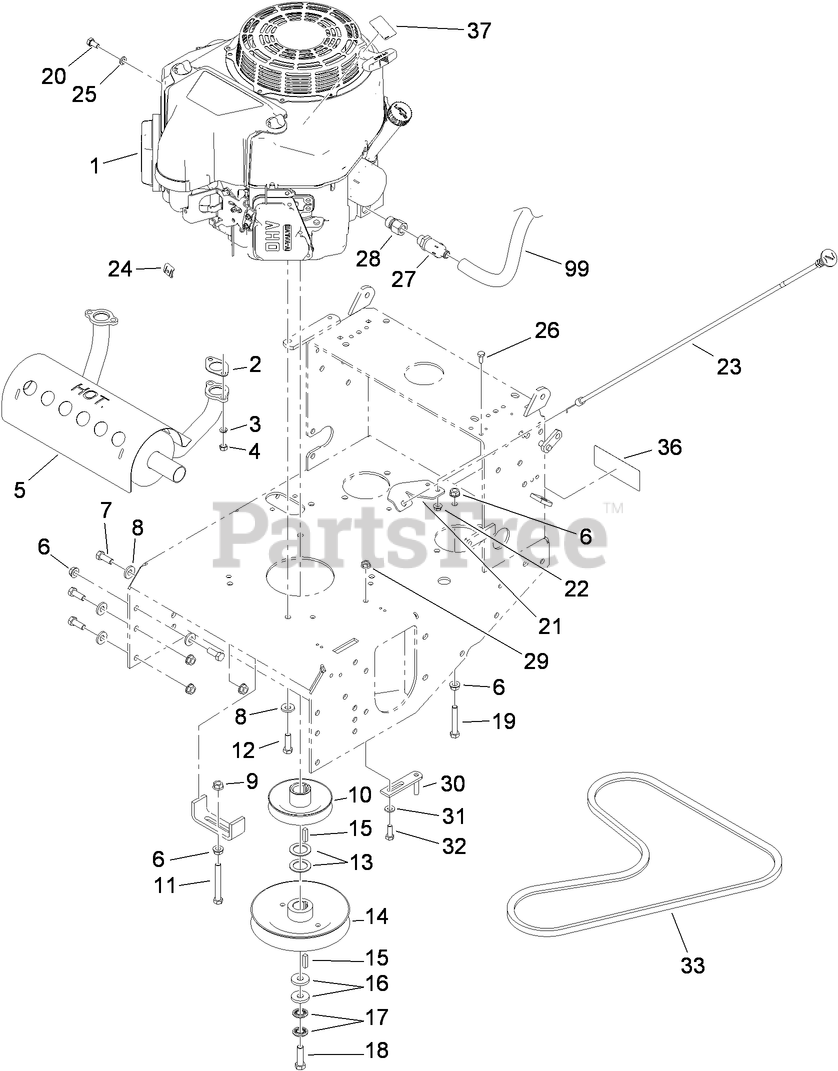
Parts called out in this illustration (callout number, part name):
2	GASKET-EXHAUST
3	WASHER-LOCK
5	MUFFLER-HORIZONTAL, OFFSET
6	NUT-HHF, WHIZ
7	SCREW-HH
8	WASHER-BELLEVILLE
9	NUT-HF
10	PULLEY
11	SCREW-HH
12	SCREW-HH
13	WASHER-SPACER
14	PULLEY ASM
16	WASHER
17	WASHER-SPRING
18	SCREW-HH
19	SCREW-HH
20	SCREW-HH
21	Bracket-Cable, Choke
22	NUT-HF
23	Cable-Choke
24	CLAMP-CABLE
25	WASHER-LOCK
26	SCREW-HH
27	VALVE-DRAIN, OIL
28	Adapter
29	NUT-HF
30	GUIDE-BELT
31	WASHER-SPRING
32	SCREW-HH
33	BELT-V
36	DECAL-CAUTION
37	DECAL-WARNING
99	HOSE-DRAIN, OIL
